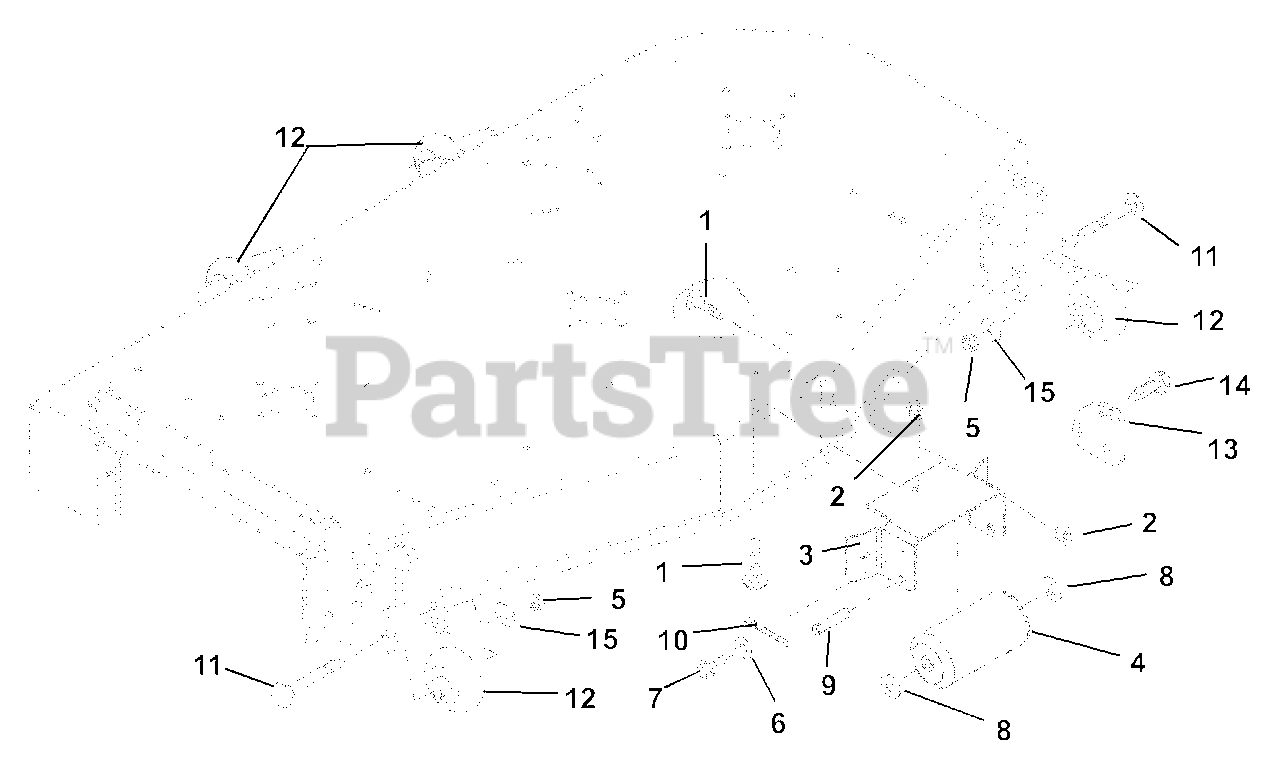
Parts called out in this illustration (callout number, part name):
1	Bolt, Round Head Square Neck .38-16 x 1.00 Grade 5 (064, 077, 078,
1	Bolt, Round Head Square Neck .38-16 x 1.25 Grade 2
2	Nut, Locking Top Flange, .38-16
3	Bracket, Anti-Scalp Roller
5	Nut, Locking Nylon .50-13
6	Washer, Flat Steel .281 x .62 x .065
7	Screw, Tapping .25-20 x .75 Hex Washer Head
8	Washer, Flat Steel .656 x 1.31 x .095
10	Pin, Cotter .25 x 2.0
11	Bolt, Round Head Square Neck .50-13 x 5.00 Grade 2
12	Wheel, 3 x 5
13	Anti-Scalp Washer
14	Screw, Tapping .25-20 x .62 Hex Washer Head
15	Washer, Flat Steel .531 x 1.06 x .095
